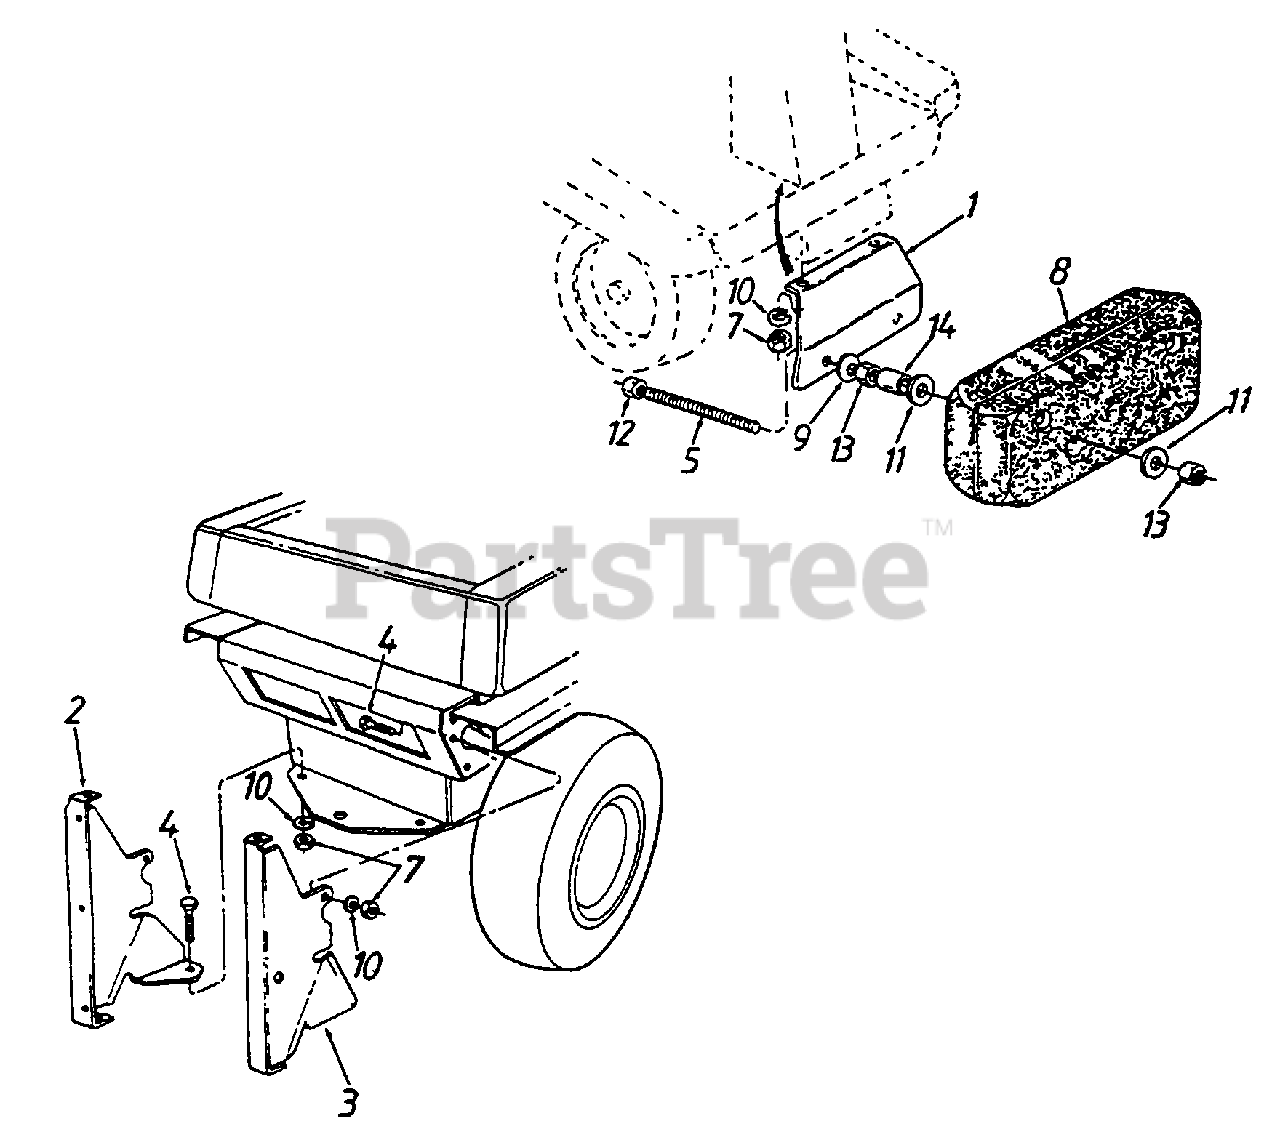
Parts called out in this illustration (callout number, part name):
3	Catcher Support Brkt.- L.H.
4	Hex Bolt 5/16-18 x 1.0" Lg.
5	Stud 7/16-14 x 5-5/8" Lg.
7	Hex Nut 5/16-18 Thd. (Gr. 5)
8	Front Counterweight
9	Bell-Wash. 7/16" I.D.
10	L-Wash. 5/16" I.D.
11	Fl-Wash .45" I.D.
12	Hex L-Nut 7/16-14 Thd.
13	Hex Nut 7/16-14 Thd.
14	Spacer
